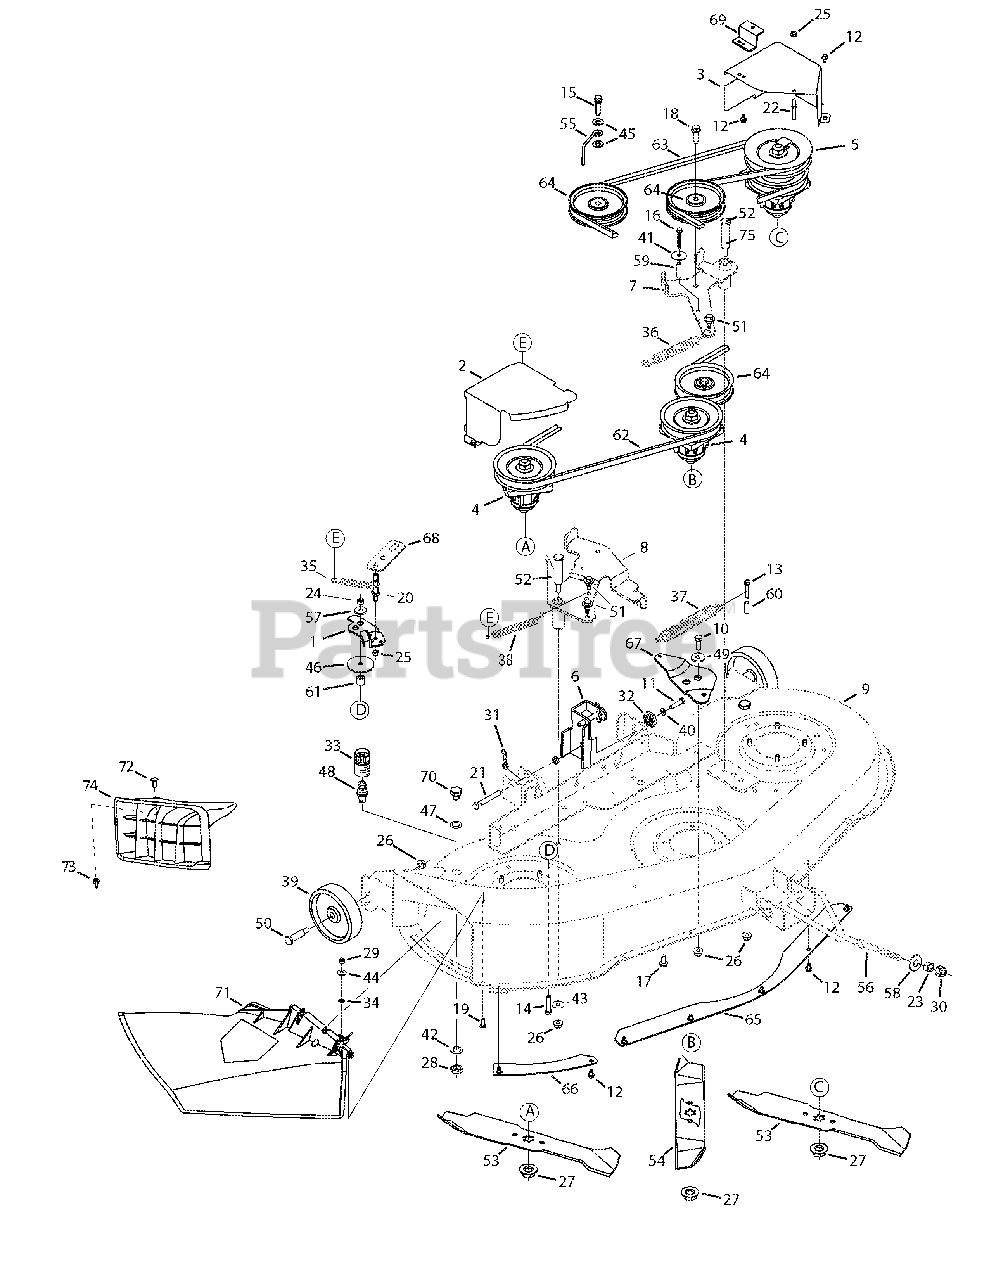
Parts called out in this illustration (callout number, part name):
1	Deck Brake Assembly
4	Spindle Assembly
5	Double Pulley Spindle Assy.
11	Hex Screw, 5/16-18 x 1.25
12	Screw, 1/4-20 x .50
13	Screw, 1/4-20 x 1.50
14	Hex Screw, 5/16-18 x 1.50
15	Sems Screw, 3/8-16 x 1.50
16	Screw, 1/4-20 x 1.75
17	Screw, 5/16-18, .750
18	Screw, 3/8-16, x 1.25
19	Screw, 1/4-20 x .75
20	Pin, 1/4-20: 3/8 x 2.685
21	Clevis Pin, 3/8 dia. x 2.75
22	Belt Guard Pin, 1/4 x 1.43 lg.
23	Hex Nut, 1/2-13
24	Flange Lock Nut, 5/16-18
25	Flange Lock Nut, 1/4-20
26	Flange Lock Nut, 3/8-16
27	Flange Nut, 5/8-18
28	Hex Nut, M16-1.5
29	Hex Nut, 1/4-20
30	Hex Lock Nut, 1/2-13
31	Bow-Tie Cotter Pin
32	Deck Adjustment Gear
33	Water Nozzle Adapter
34	Push Nut, .25 ID x .50 OD
35	Extension Spring, .50 x 3.97 Lg.
36	Extension Spring, .75 x 6.835 Lg.
37	Extension Spring, .91 x 7.33 Lg.
38	Extension Spring, .56 x 5.52 lg.
39	Deck Wheel 5.0 x 1.38
40	Lock Washer, 5/16
41	Flat Washer, .285 x 1.25 x .06
42	Lock Washer, 5/8 Int. Tooth
43	Flat Washer, .385 x 1.0 x .135
44	Bell Washer, .265 x .75 x .062
45	Flat Washer, .406 x .875 x .059
46	Flat Washer, .406 x .875 x .059
47	Flat Washer, .64 x 1.24 x .06
48	Deck Water Nozzle
49	Shoulder Spacer, .625 ID x .169
50	Shoulder Bolt .496 x 1.525: 3/8-16
51	Shoulder Screw .43 x .29:5/16-18
52	Shoulder Bolt .625 x 2.515: 3/8-16
53	Blade, 3 in 1 star, 16.28" Lg.
54	Blade, 3 in 1 star, 14.88" Lg.
55	Belt Keeper Rod
56	Front Deck Adjustment Rod
57	Shoulder Spacer
58	Deck Lift Pivot Cup
59	Spacer, .260 x .372 x 1.420 Lg.
60	Spacer, .260 x .372 x 1.030 Lg.
61	Spacer, .375 x .63 x .595 Lg.
62	V-Belt, 79.10 Lg.
63	V-Belt, 91.4 Lg.
64	Idler Pulley, 4.25" dia.
70	Bolt Plug, M16 x 1.5
71	Discharge Chute
72	Carriage Screw, 1/4-20 x .62
73	Wing Nut, 1/4-20
74	Mulch Plug, 46" Deck
75	Spacer, .380 x .625 x 2.515 Lg.
